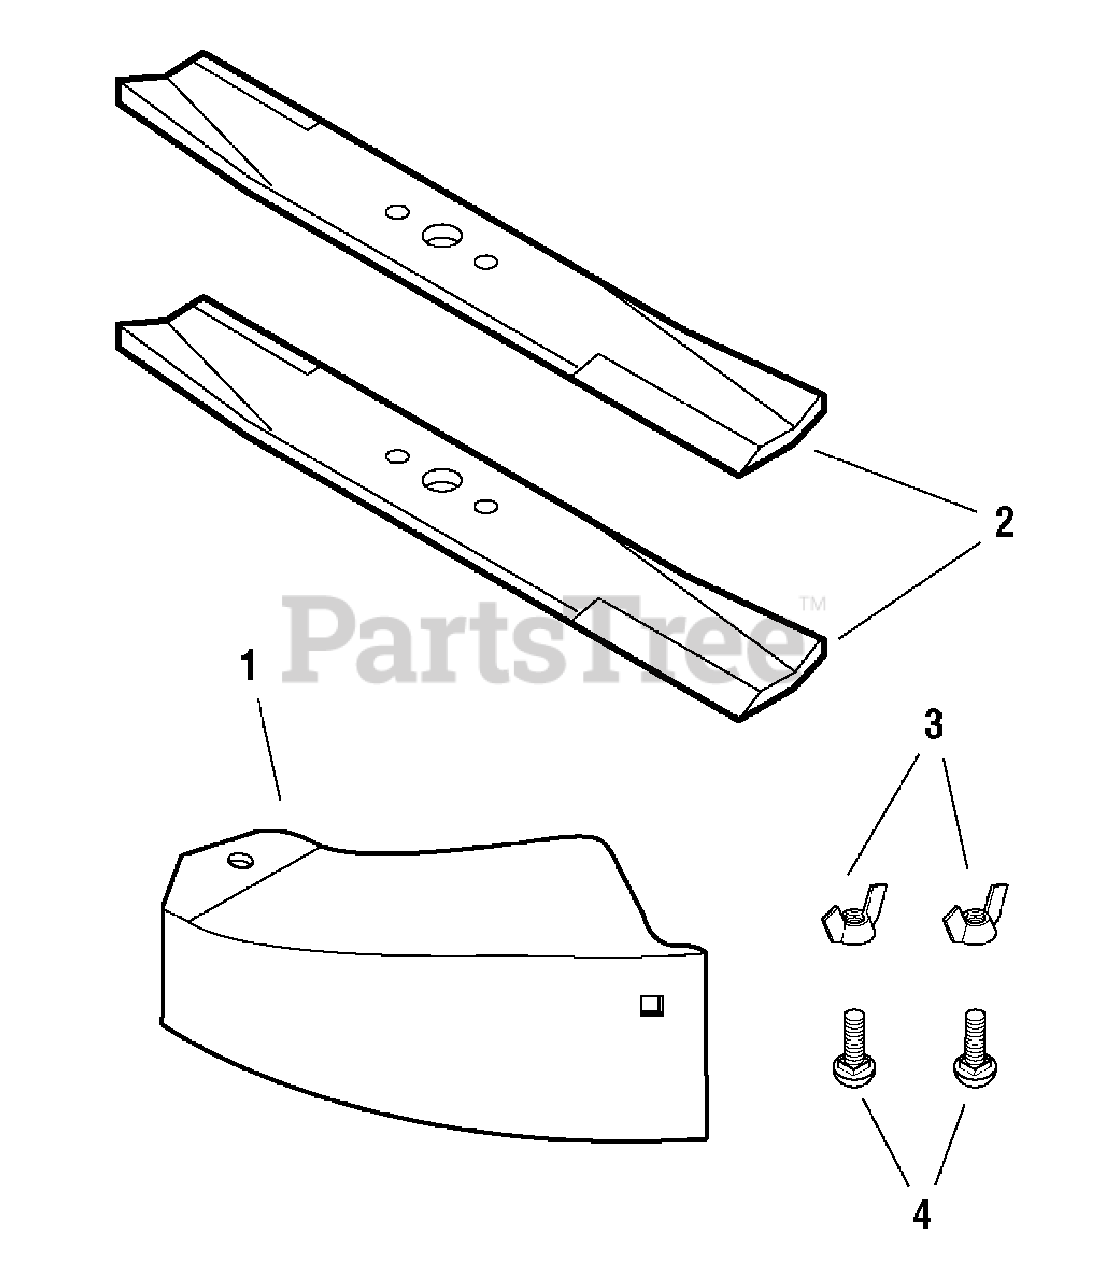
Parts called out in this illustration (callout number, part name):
1	COVER, Mulch
2	NUT, Wing, 5/16-18
3	BOLT, Carriage, 5/16-18 x 3/4
4	BLADE, 42" Mower Deck
5	NUT, Push, 5/16
6	KNOB, Plastic, 5/16-18
